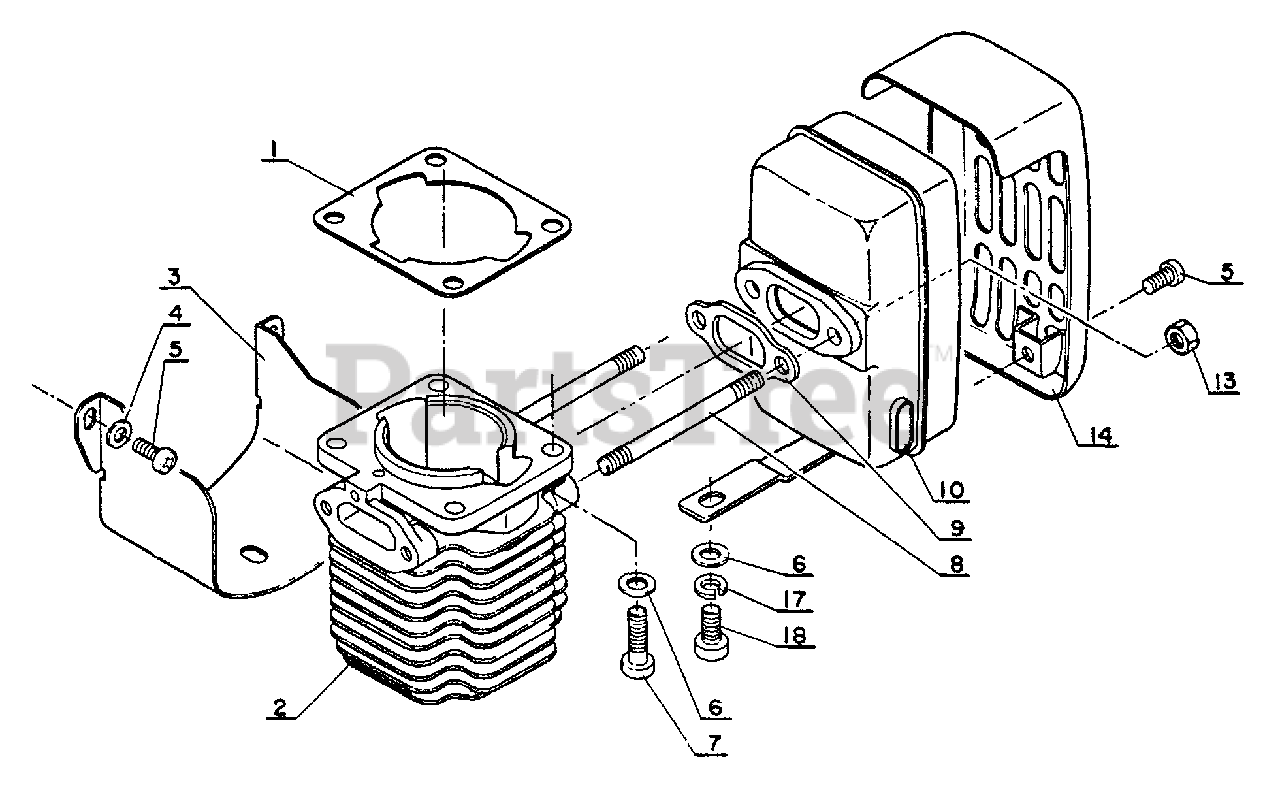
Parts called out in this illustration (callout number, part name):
1	GASKET, CYLINDER
2	CYLINDER
3	SHIELD, CYLINDER
4	WASHER - 4
5	SCREW - 4X8
6	WASHER - 5
7	SCREW - 5X16
8	STUD
9	GASKET, EXHAUST
10	MUFFLER
13	LOCKNUT - 5
14	COVER, MUFFLER
17	LOCKWASHER - 5
18	SCREW - 5X10
